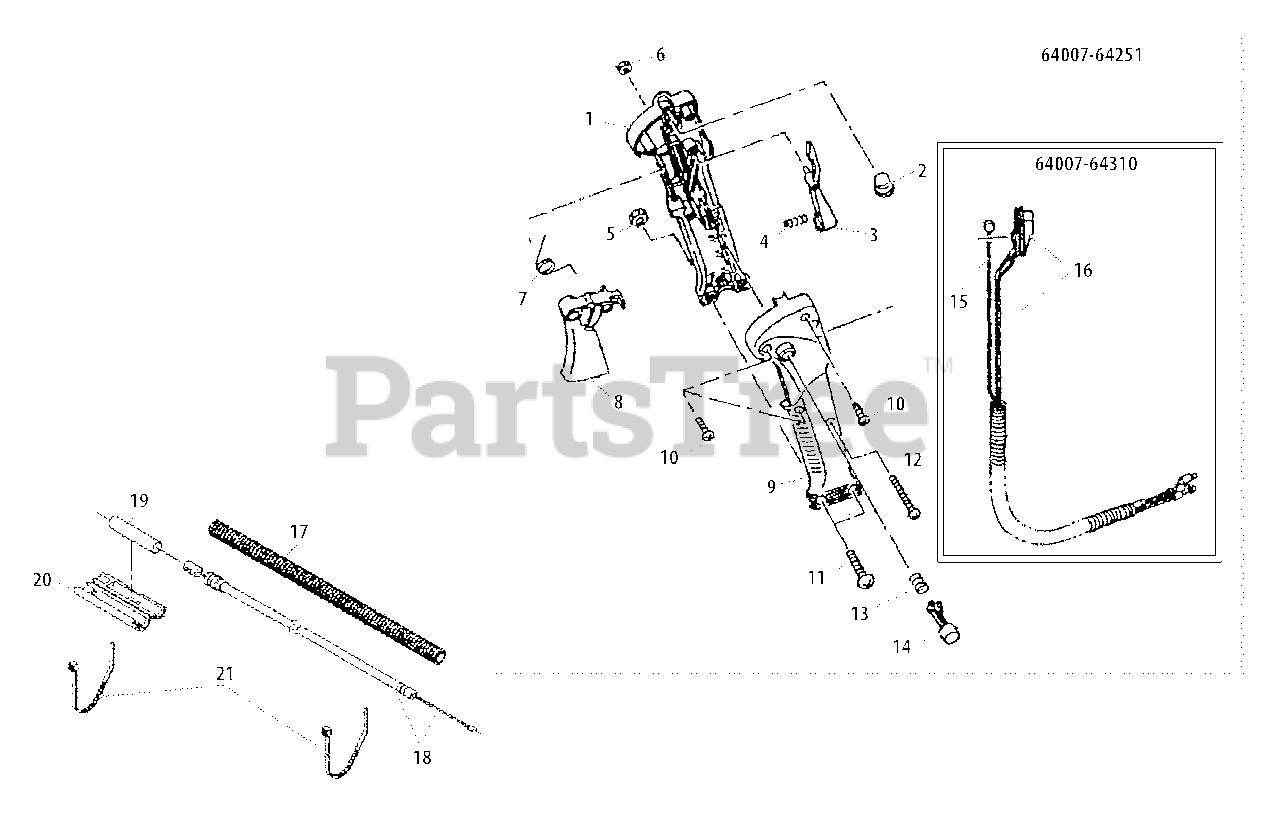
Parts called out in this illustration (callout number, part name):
1	HANDLE, CONTROL - RIGHT
2	PLUG
3	LEVER, TRIGGER LOCKOUT
4	SPRING
5	NUT - 5
6	NUT - 4
7	SPRING
8	TRIGGER, THROTTLE
9	HANDLE, CONTROL - LEFT
10	SCREW - 4X16 -- TAPPING
11	SCREW - 5X20
12	SCREW - 4X23
13	SPRING
14	BUTTON, THROTTLE LOCK
15	CABLE, THROTTLE - A
16	SWITCH
17	TUBE, PROTECTIVE - CORRUGATED
18	THROTTLE CABLE B
19	SLEEVE
20	CONNECTOR TUBE
21	TIE, CABLE
64007-64251	THROTTLE LEVER ASSY
64007-64310	CONTROL CABLE ASSY
